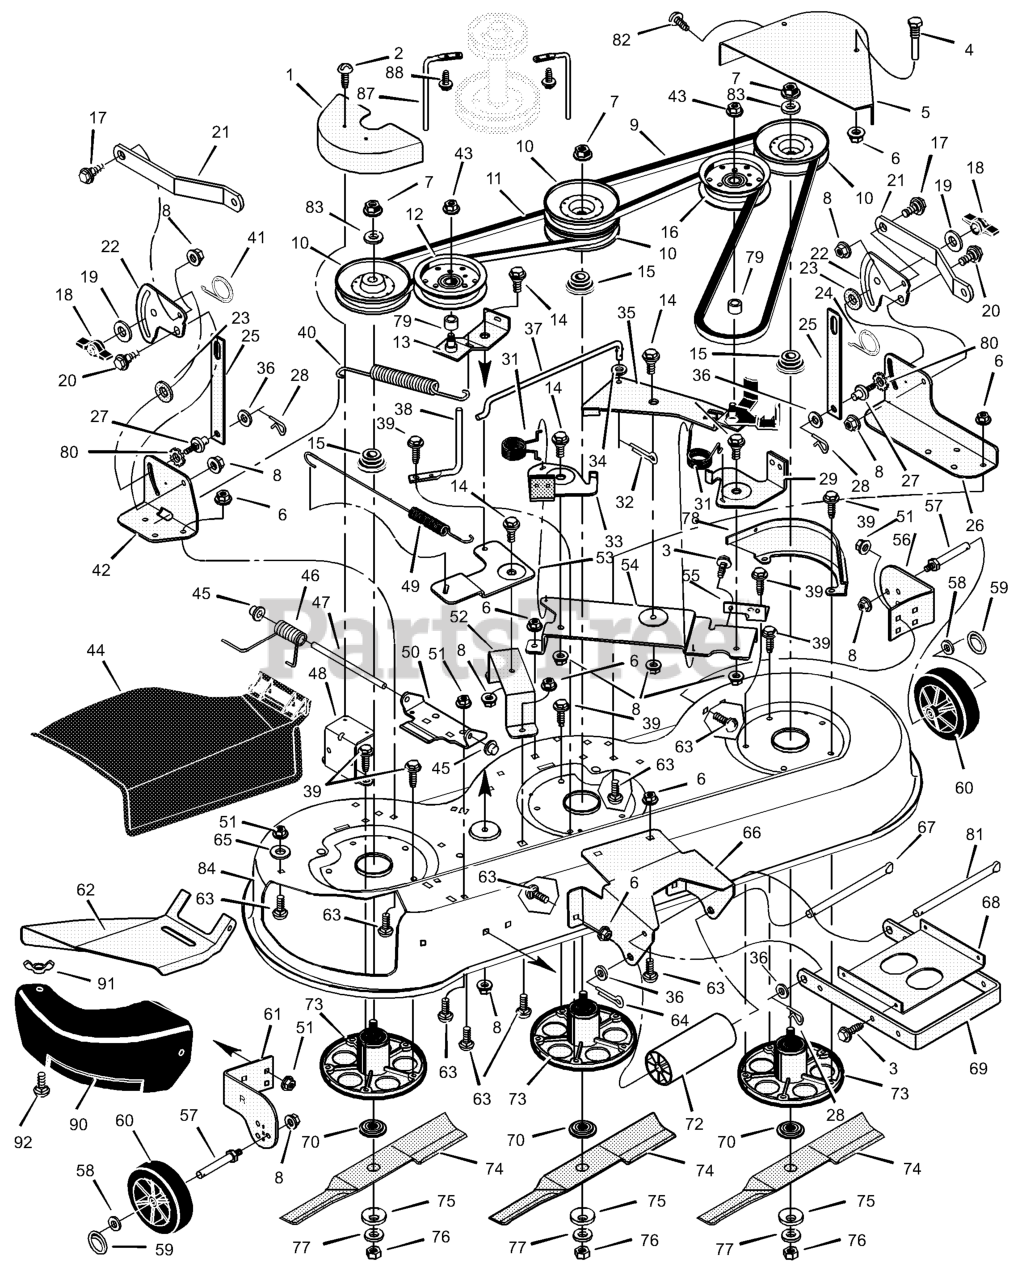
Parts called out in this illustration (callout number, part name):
1	Cover, Right Pulley
2	Screw
4	Guide, Belt
5	Cover, Left Pulley
6	Nut, Hex
7	Nut, Flange
8	Nut, Flange
9	Belt, Primary
10	Pulley
11	Belt, Secondary
12	Pulley, Idler
13	Arm, Idler
14	Bolt, Shoulder
15	Spacer, Pulley
16	Pulley, Idler
17	Bolt, Shoulder
18	Knob
20	Bolt, Shoulder
21	Bracket, Rear Suspension
22	Plate, Suspension
23	Pad, Friction
25	Link, Lift
26	Bracket, Left Lift
27	Pin, Hanger
28	Pin, Hair
29	Brake Assembly, Left
32	Pin, Cotter
33	Brake Assembly, Right
34	Washer
35	Idler, Arm
37	Link, Bell Crank
38	Guide, Belt
39	Screw
40	Spring, Extension
41	Spring, Torsion
42	Bracket, Suspension
43	Nut
44	Deflector, Chute
45	Push On Cap
46	Spring, Torsion
47	Rod, Deflector
48	Bracket, Cover
49	Spring, Extension
50	Bracket, Hinge
51	Nut, Flange
52	Bracket, Bell Crank
53	Crank, Bell
54	Plate, Brake Arm
55	Bracket, Brake Plate
56	Bracket, Left Gauge Wheel
57	BOLT, Gauge Wheel
59	Ring, Locking
60	Wheel, Gauge
61	Bracket, Right Gauge Wheel
62	Deflector, Inside
63	Bolt, Carriage
64	Pin, Cotter
66	Bracket, Front Deck
67	Rod, Hanger
68	Stiffener
69	Bracket, Suspension
70	Adapter, Blade
73	Housing, Jackshaft
75	Washer, Belleville
78	Bracket, Pulley Cover
81	Rod, Hanger
83	Washer
84	Housing, Blade
87	Guide, Belt
88	Screw
90	Cover, Mulch
91	Wingnut
92	Bolt, Carriage
